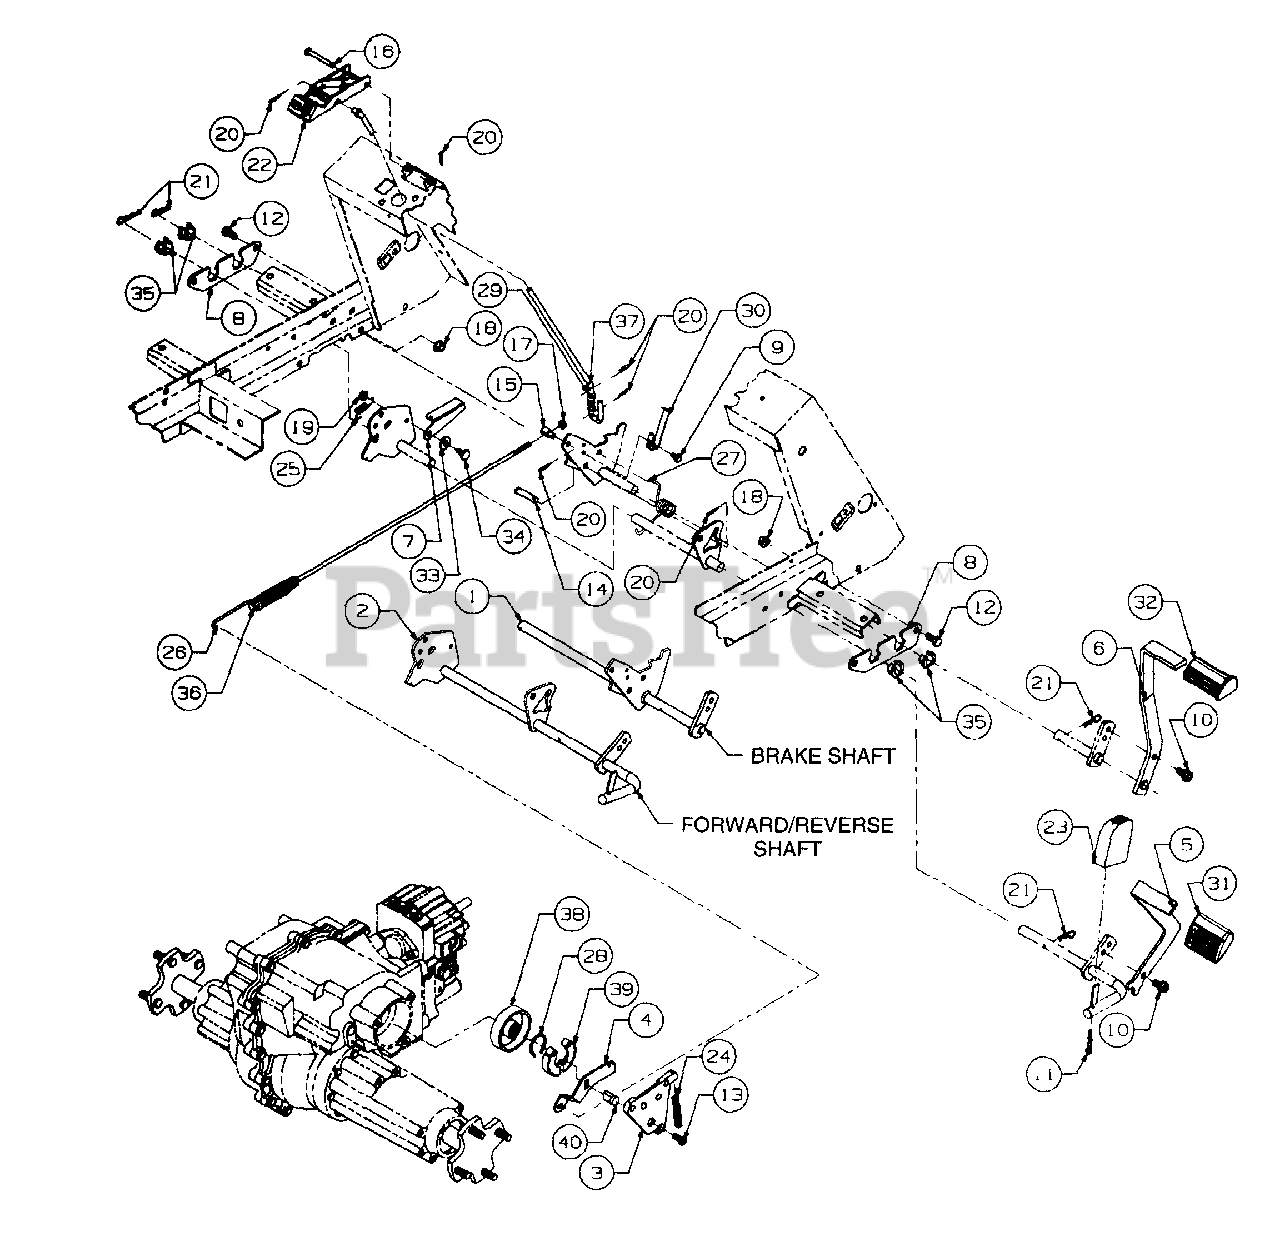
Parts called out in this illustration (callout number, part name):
1	Shaft Assy, Brake
2	Shaft Assy, Forward/Reverse
3	Plate, Brake
4	Arm, Brake
5	Pedal, Forward
6	Pedal, Brake
7	Actuator, Reverse Switch
8	Plate, Bearing Mounting
9	Screw, Hex Wash Tapp, 1/4 x .50 Lg
10	Screw, Hex Wash Tap, 3/8-16 x .75 Lg
11	Screw, Truss Mach Tapp, #12 x 1.5
12	Screw, Hex Cap, 3/8-16 x .75 GR5
13	Screw, Low Hd Cap, 3/8-16 x .75
14	Pin, Clevis, 3/8 OD x 1.62 Lg
15	Ferrule, Adjustment
16	Pin, Clevis, 1/4 OD x 2.38 Lg
17	Nut, Hex Sems, 1/4-20
18	Nut, Hex Flanged Lock, 3/8-16
19	Nut, Hex Flange Lock, 1/4-20
20	Pin, Internal Cotter, 5/16 Dia x 1.12
21	Pin, Internal Cotter, 3/8 Dia x 1.625
22	Lever, Park Brake
23	Pad, Reverse Pedal
24	Spring, Compression
25	Spring, Extension, .38 OD x 2.10 Lg
26	Spring, Extension, .75 OD x 5.0 Lg
27	Spring, Torsion
28	Spring, Brake
29	Spring, Compression, .5 OD x 2.23
30	Actuator, Neutral Switch
31	Pad, Forward Pedal
32	Pad, Brake Pedal
33	Washer, Flat, .406 x .75 x .063
34	Bolt, Shoulder, .375 Dia x .181 Lg
35	Bearing, Hex Flange Split
36	Rod, Brake
37	Rod, Park Brake Engagement
38	Drum, Brake
39	Shoe, Brake
40	Actuator, Brake Shoe
